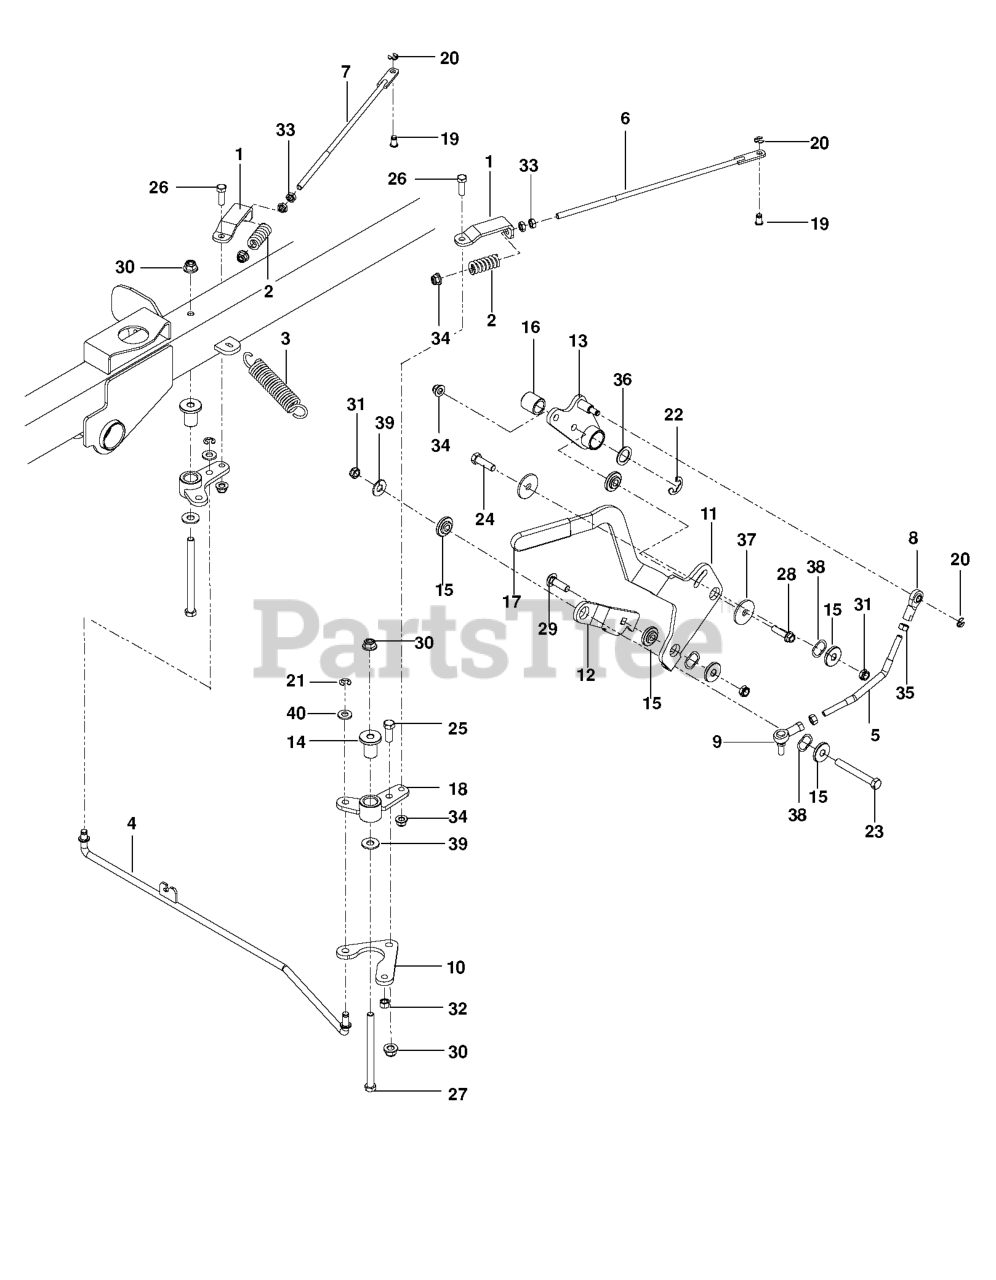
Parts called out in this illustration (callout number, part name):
1	BRACKET, BRAKE
4	LINKAGE, BRAKE, PRIMARY
5	LINKAGE, BRAKE
6	LINKAGE, BRAKE RR
7	LINKAGE, BRAKE, RT-RR
8	BALL JOINT, RIGHT HANDED
9	SPHERICAL ROD END, RH
10	PLATE, BRAKE, BLK
11	LEVER.BRAKE.BLACK
12	LINK, FOLLOWER
13	WELDMENT, ARM, BRAKE
14	BUSHING, PIVOT
15	BUSHING, BRAKE
16	BUSHING, SLEEVE 3/4 X 1.0
18	BELLCRANK, BRAKE, WLDMT
19	PIN, BRAKE ARM
20	RING RETAINING EXT 5/16
21	E RING 3/8"
22	E RING 3/4
23	HCS 3/8C X 3
24	HCS 3/8C X 1 1/4 GR5
25	HCS 3/8-16X1.GRD.5.ZD
26	HCS 5/16C X 1
27	SCREW, 3/8C X 5 HEX CAP
28	HHFS 5/16-18 X 1.25 TPBLT GD 5
29	RHSNB 3/8-16 X 1-1/4
30	NUT 3/8-16 HEX FLG NYLOC ZD
31	NUT HEX 3/8-16 NYLON, THIN
32	NUT 5/16F NYLOC
33	NUT 5/16-18 HEX JAM ZD
34	5/16-18 NYLOC FLANGE NUT
36	WASHER .787 X 1.125 X .06
37	WASHER, FRICTION, 1/8
38	WASHER, .825 X 1.087, WAVE
39	WASHER 3/8 FLAT
40	WASHER 3/8 SAE FLAT
